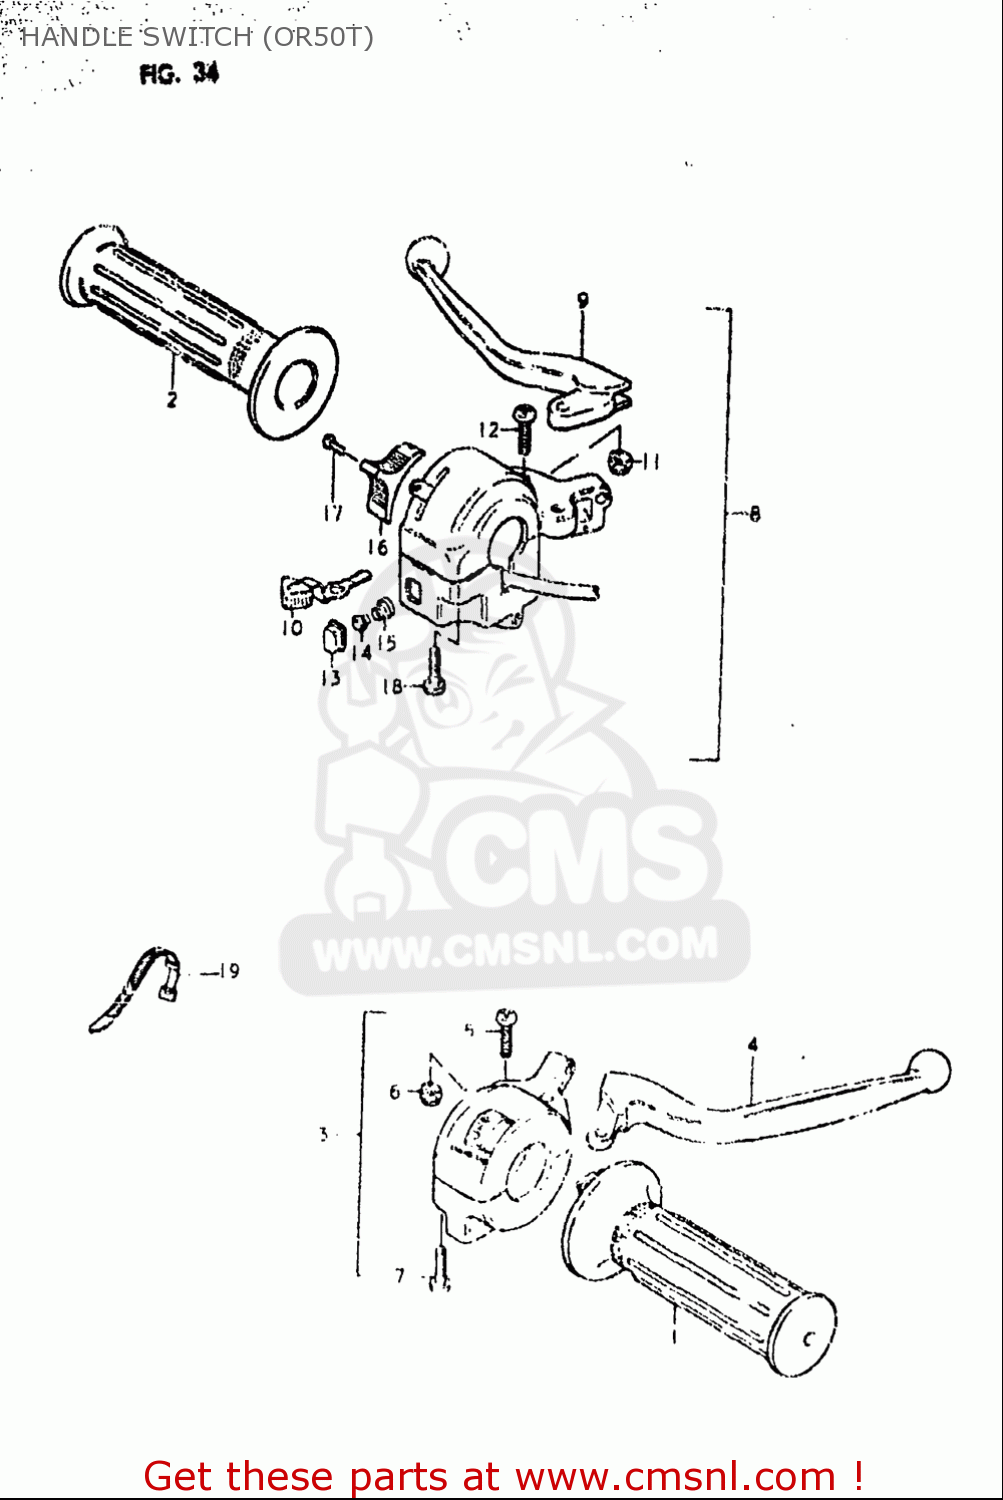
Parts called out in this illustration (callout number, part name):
1	GRIP,THROTTLE
2	GRIP,L
4	LEVER
5	BOLT,LEVER PIVOT
6	NUT
7	SCREW
9	LEVER
10	KNOB,TURN SIGNAL SWITCH
11	NUT
12	BOLT,LEVER PIVOT
13	BUTTON,HORN
14	CONTACT
15	SPRING
16	KNOB
17	SCREW
18	SCREW
19	CLAMP(L:120)
